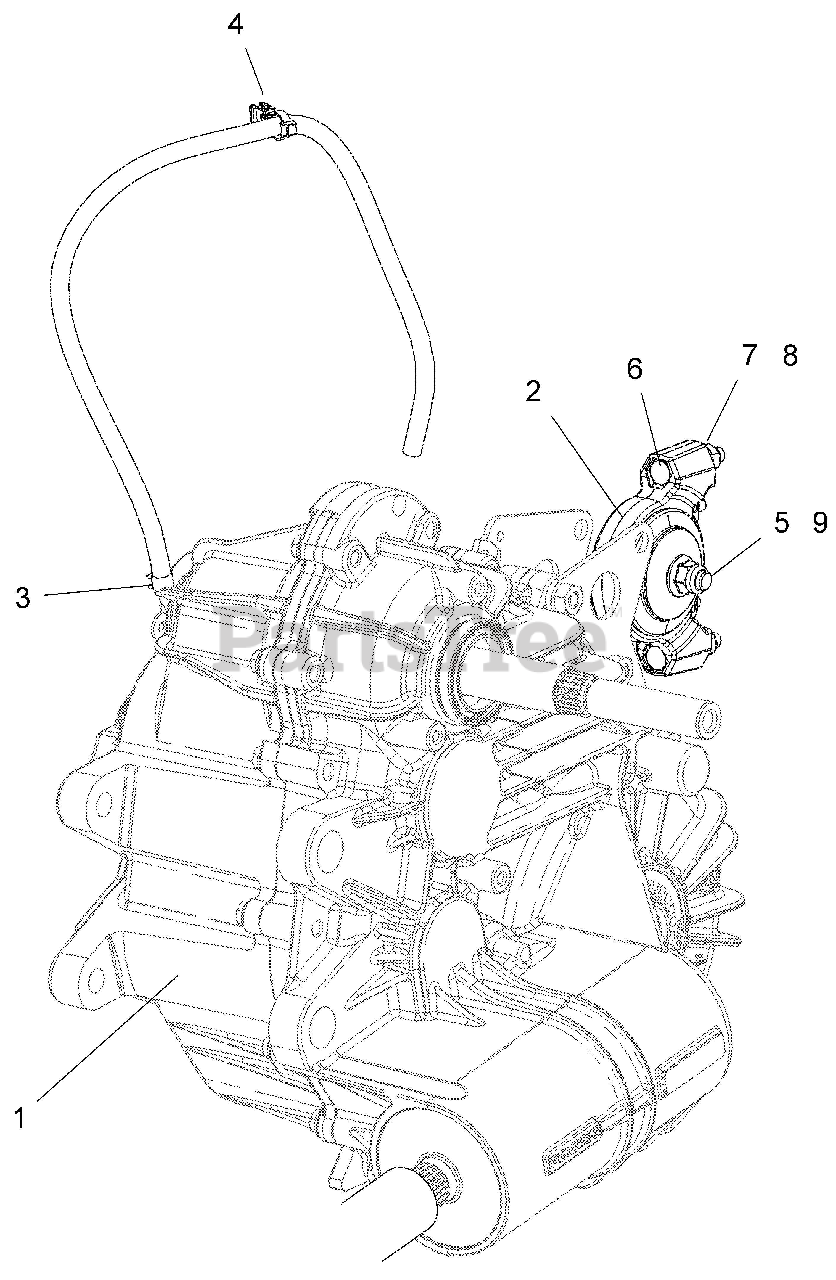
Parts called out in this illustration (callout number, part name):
1	ASM-GEARCASE,DSL
2	MOUNT-ISOLATOR,DRIVELINE
3	CLAMP,HOSE(10)
4	STRAP-CABLE TIE W/EDGE CLIP
5	BOLT-M10X1.25X60,HXFLG-OLIVE D
6	SCR-HH M8X1.25X45 8.8 ZOD
8	NUT-M8X1.25,FLG,NYLOC-OLIVE D
9	NUT-M10X1.25,FLG,NYLOC-OLIVE D
